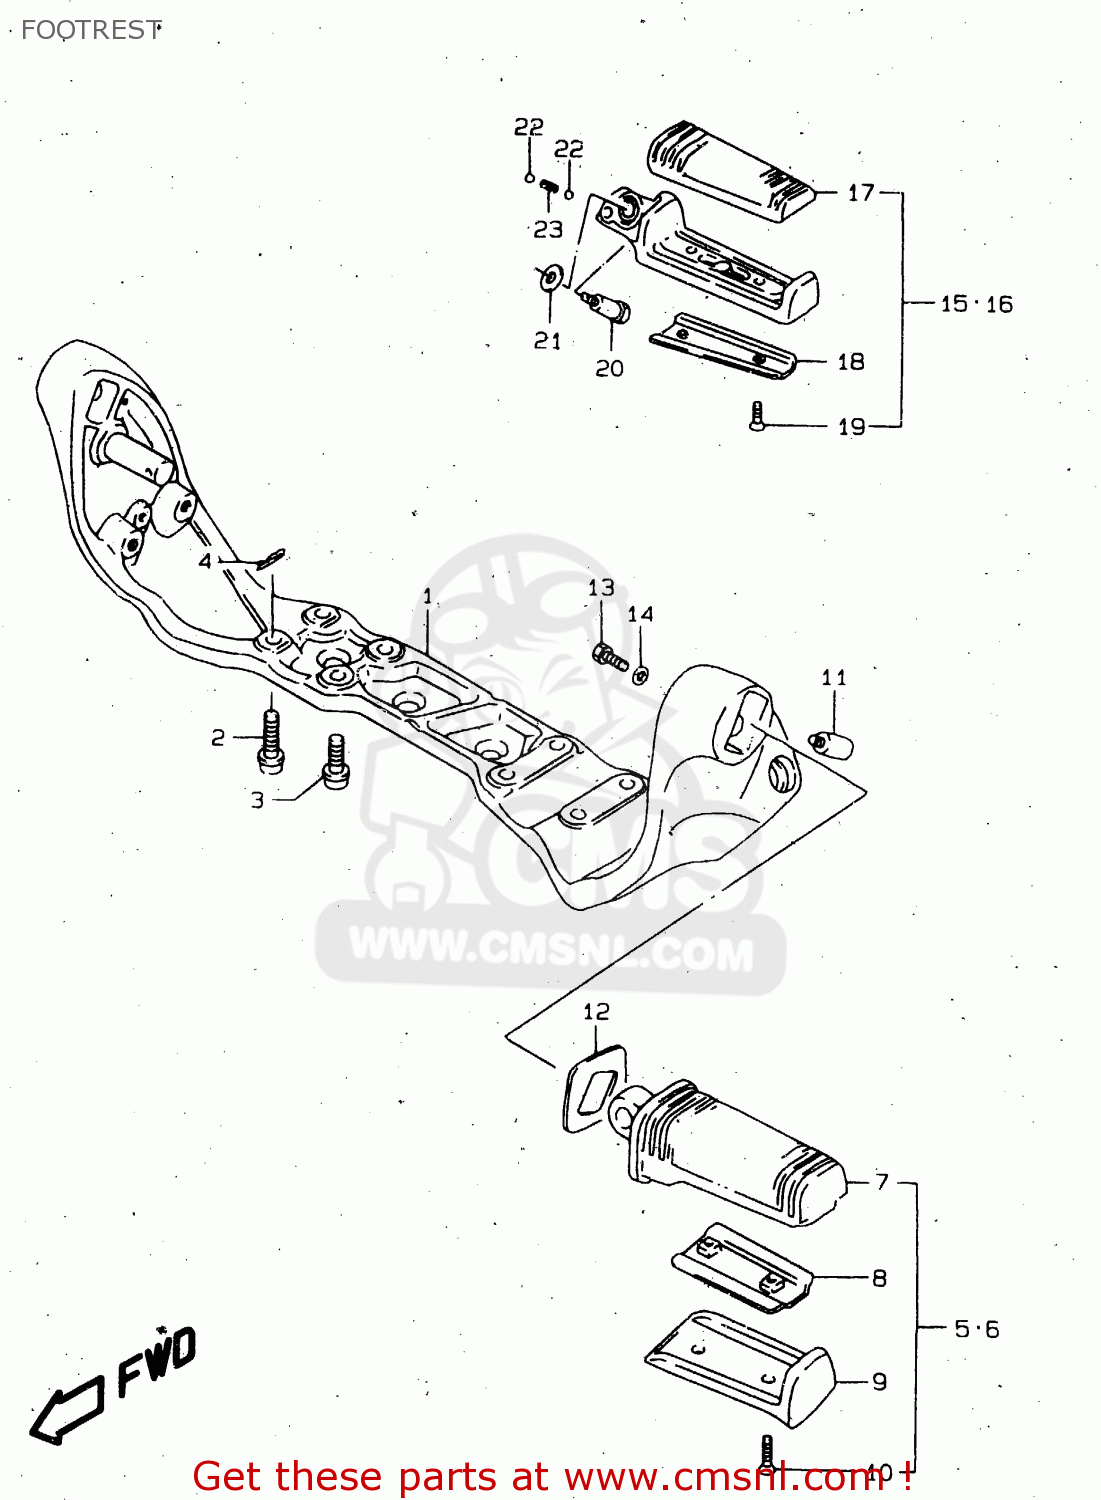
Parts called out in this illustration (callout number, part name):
1	BRACKET,FRONT FOOTREST
2	BOLT(8X25)
3	BOLT
4	SNAP
5	FOOTREST ASSY,FR,R
6	FOOTREST ASSY,FR,L
7	RUBBER,FR FOOTREST
8	PLATE,RUBBER STOPPER
9	COVER,FR FOOTREST
10	SCREW(5X20)
11	BOLT,FRONT FOOTREST
12	WASHER,FR FOOTREST
13	BOLT
14	LOCK,WASHER
15	FOOTREST ASSY RH
16	FOOTREST ASSY PILLION LH
17	RUBBER,PILLION FOOTREST
18	PLATE,RUBBER STOPPER
19	SCREW(5X16)
20	BOLT(6X34.5)
21	SHIM
22	BALL
23	SPRING
